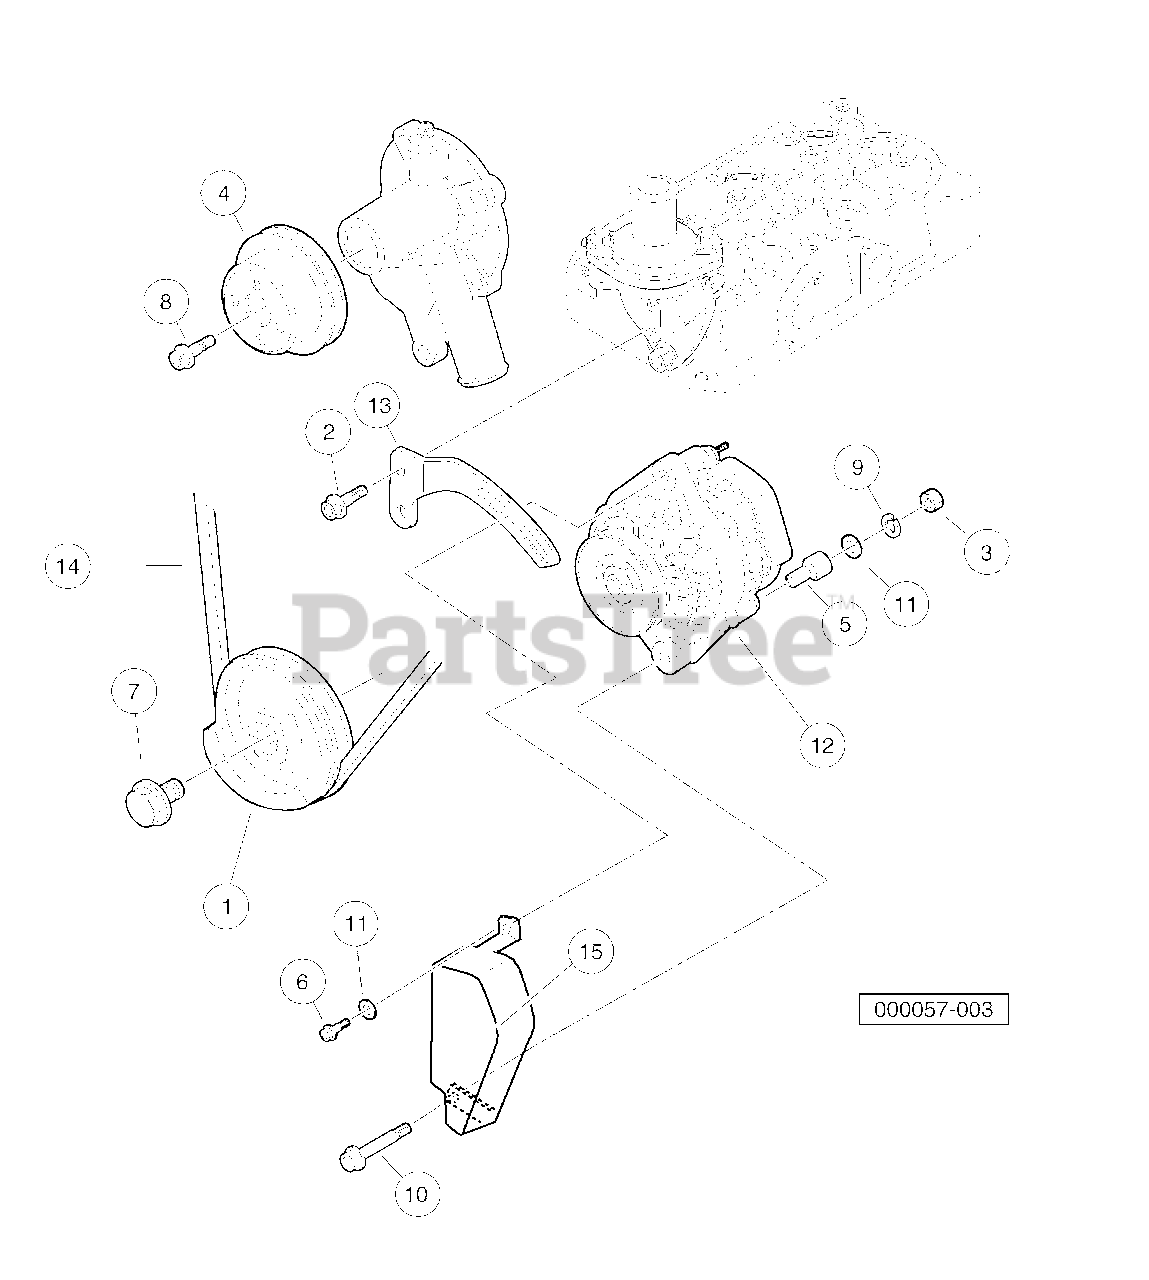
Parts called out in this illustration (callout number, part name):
1	Pulley, Fan Drive
2	Bolt, M6 X 1 X 20
3	Nut, M8, Plate
4	Pulley, Water Pump
5	Collar, Alternator Assy, D722
6	Bolt, Alt, D722, Adjuster
7	Bolt, Alt, D722, Drive Pulley
8	Bolt, D722, Drive Pulley
9	Washer, Spring, D722, Starter
10	Bolt, Alternator, Lower
11	Washer, Alternator, Upper
12	Alternator, 60 Amp
13	Brkt, Alt, D722, 60 Amp
14	Belt, Acc Drive, D722, 60 Amp
15	Guard, Acc Belt
